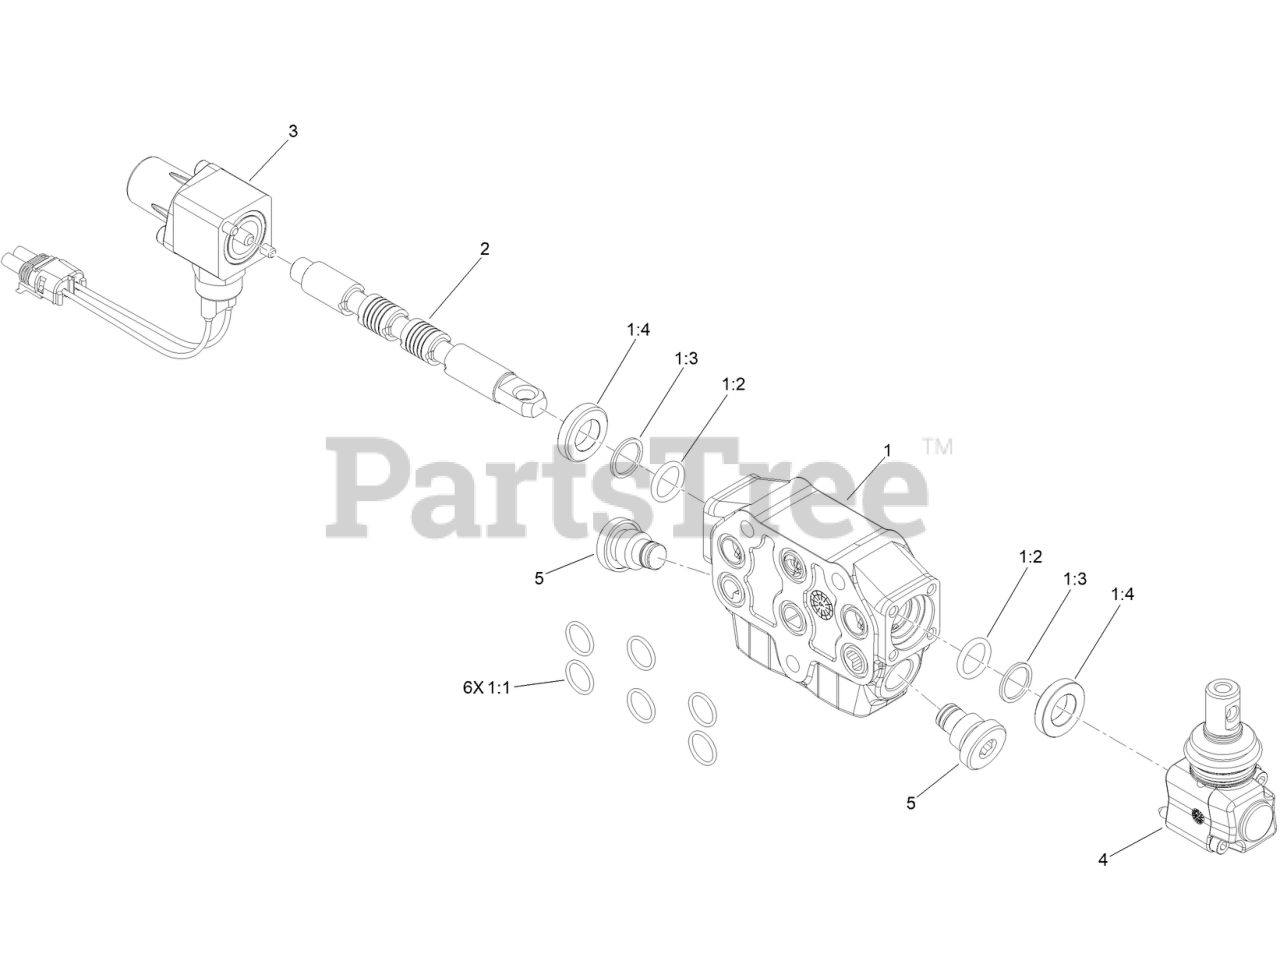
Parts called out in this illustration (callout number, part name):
1	SECTION-WORKING
1:1	O-RING
1:2	SEAL-VALVE
1:3	SEAL-VALVE
1:4	SEAL-VALVE
2	VALVE-SPOOL
3	KIT-CONTROL
4	LEVER-VALVE
